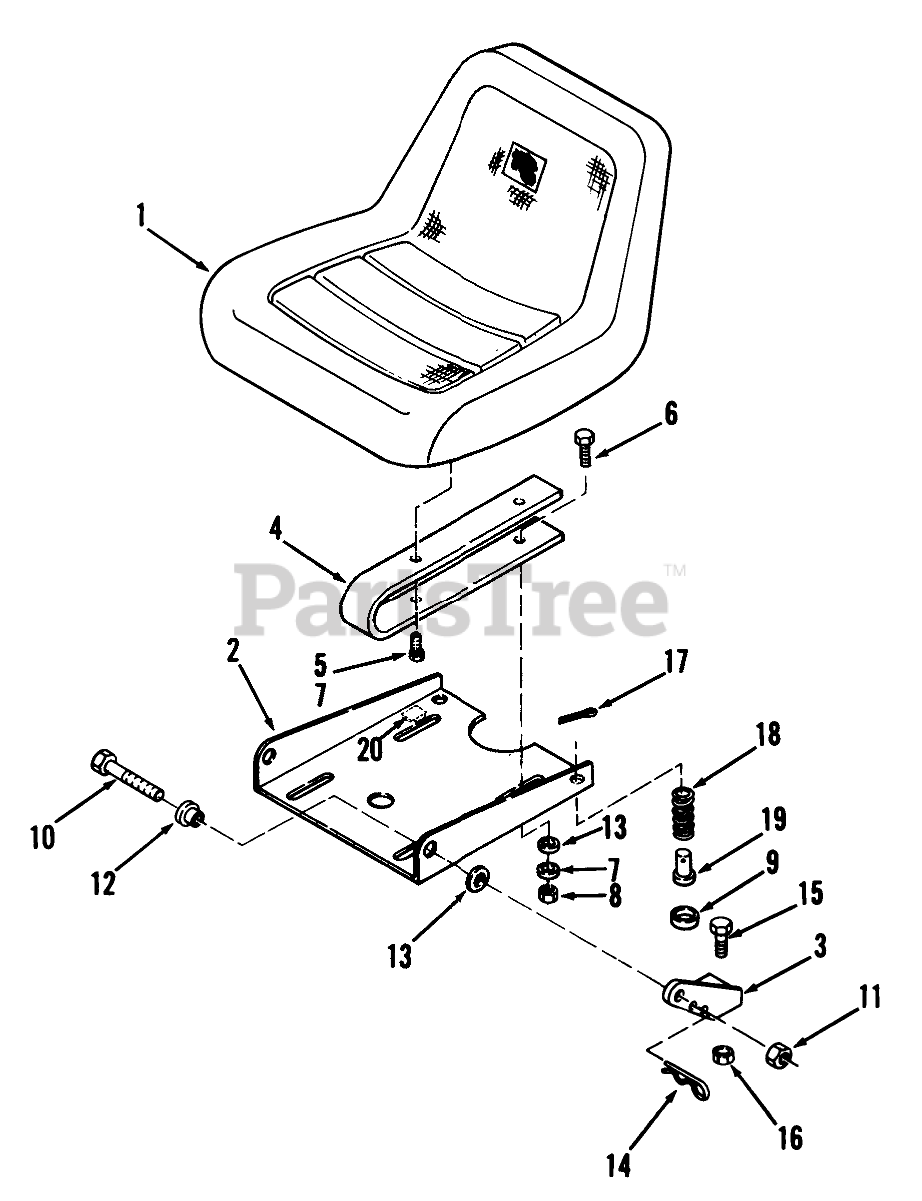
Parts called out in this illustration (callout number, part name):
12	BUSHING
13	WASHER 5/16 SAE
14	Hairpin Cotter
18	SPRING
20	BUMPER
